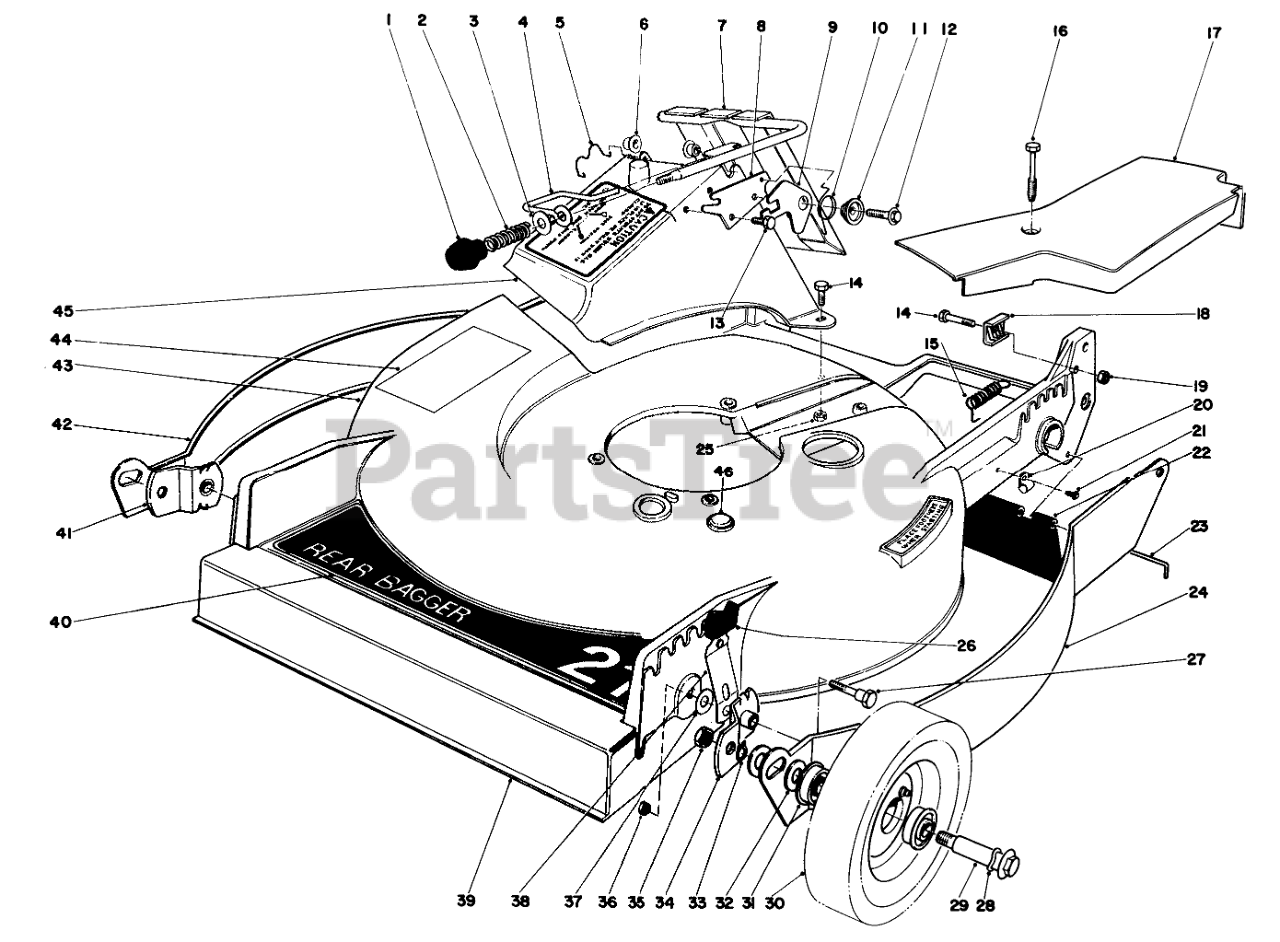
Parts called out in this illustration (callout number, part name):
2	COMPRESSION SPRING
3	WASHER
4	DOOR LATCH
5	DOOR RETAINER
6	BUSHING-NYLON
7	DOOR & HANDLE WA
8	DOOR LATCH PLATE
9	SAFETY LATCH
10	TORSION SPRING
11	Latch Spacer
12	Screw
13	SCREW-HWH
14	SCREW-HH
15	IDLER SPRING
16	SCREW-HHFTF
17	Belt Cover
18	CLAMP-CABLE
19	NUT-JAM
20	CLAMP-NYLON
21	SCREW-HWH
22	SHIELD - TRAILING
23	Rod Shield
24	LEFT SHIELD
25	NUT-LOCK, NI
26	KNOB-ARM
27	PIVOT SCREW
28	SPRING WASHER
29	WHEEL BOLT
30	Wheel & Tire Assembly (Incl. Ref. #31)
31	BEARING-BALL
32	WASHER
33	Grip Ring
34	PIVOT ARM ASM A
35	Nut
36	Nut
37	WASHER-PIVOT
38	SPRING ARM ASM (R&S)
39	FRONT SHIELD
40	Decal-Deck
41	PIVOT ARM ASM B
42	Right Shield
43	Housing
44	Decal-Caution
45	DISCHARGE CHUTE B
